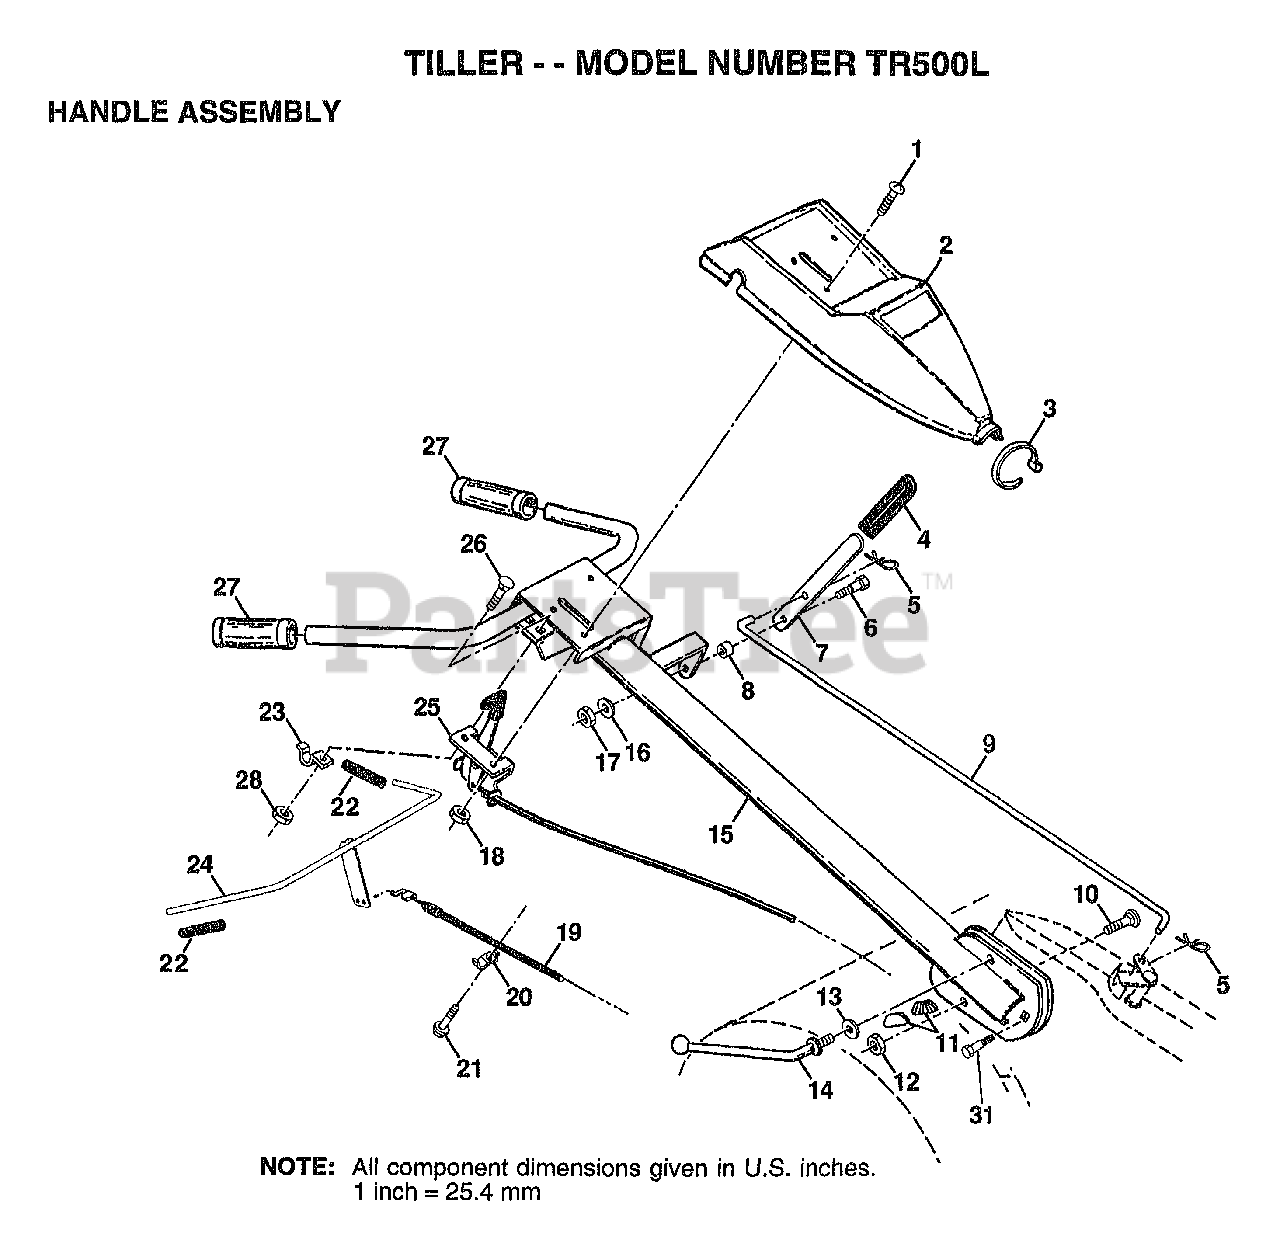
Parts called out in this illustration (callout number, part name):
1	SCREW.PNHD.10-24
2	"PANEL,CONT TI"
3	TIE CABLE CRT
4	GRIP T
5	RETAINER M
6	SHOULDER BOLT ST
7	SHIFT HANDLE CRT
8	GROMMET CRT
9	SHIFT ROD CRT
10	BOLT D
11	LOCK CRT
12	LOCKNUT
13	WASHER CRT
14	LEVER LOCK CRT
16	LOCKWASHER
19	CABLE.CLUTCH
20	CONDIUT CLIP T
22	GRIP BAR CRT
24	BAR ASM CONTROL
25	"CONT,THROTTLE"
26	BOLT
28	NUT
31	BOLT PIVOT
